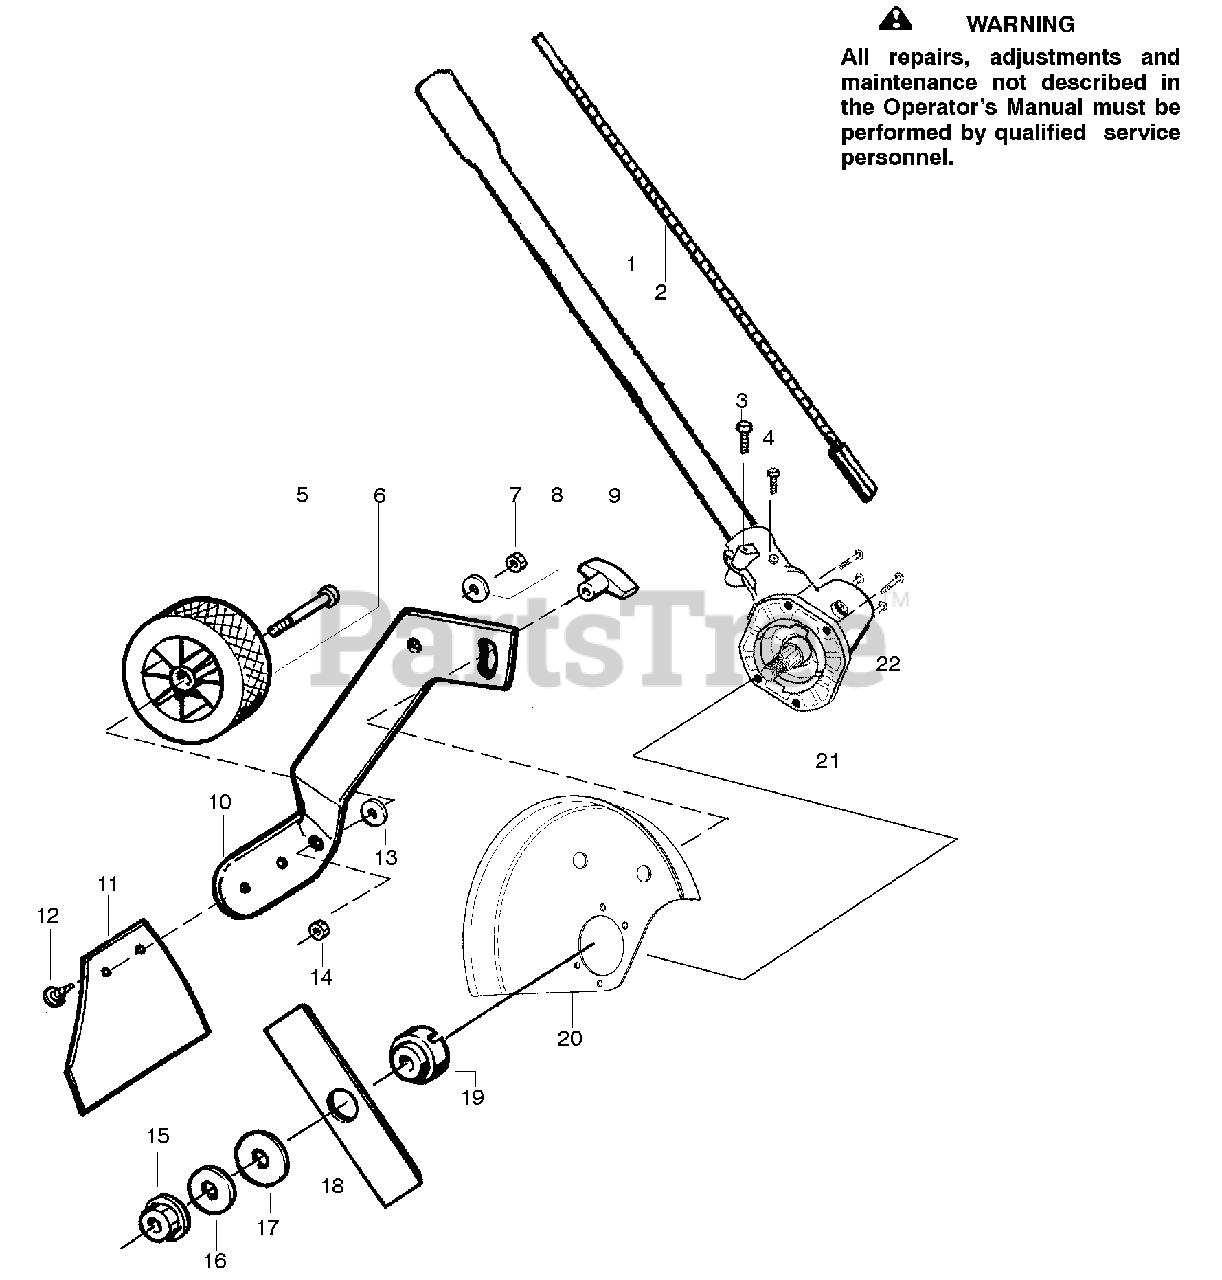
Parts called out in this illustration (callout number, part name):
1	Kit-Assy. Driveshaft
2	Flexshaft-Split boom
4	Screw-Alignment
5	Bolt-Shoulder Axle
6	Wheel-4" (rubber)
10	Bracket-Adj. Wheel
11	Kit-Mud Flap
12	Fastener-Mud Flap
15	Nut-Flange (L.H.)
16	Washer-Belleville
17	Washer-Flat
18	Accy-7.5" Blade
20	Kit-Edger Guard
21	Kit-Gearbox
